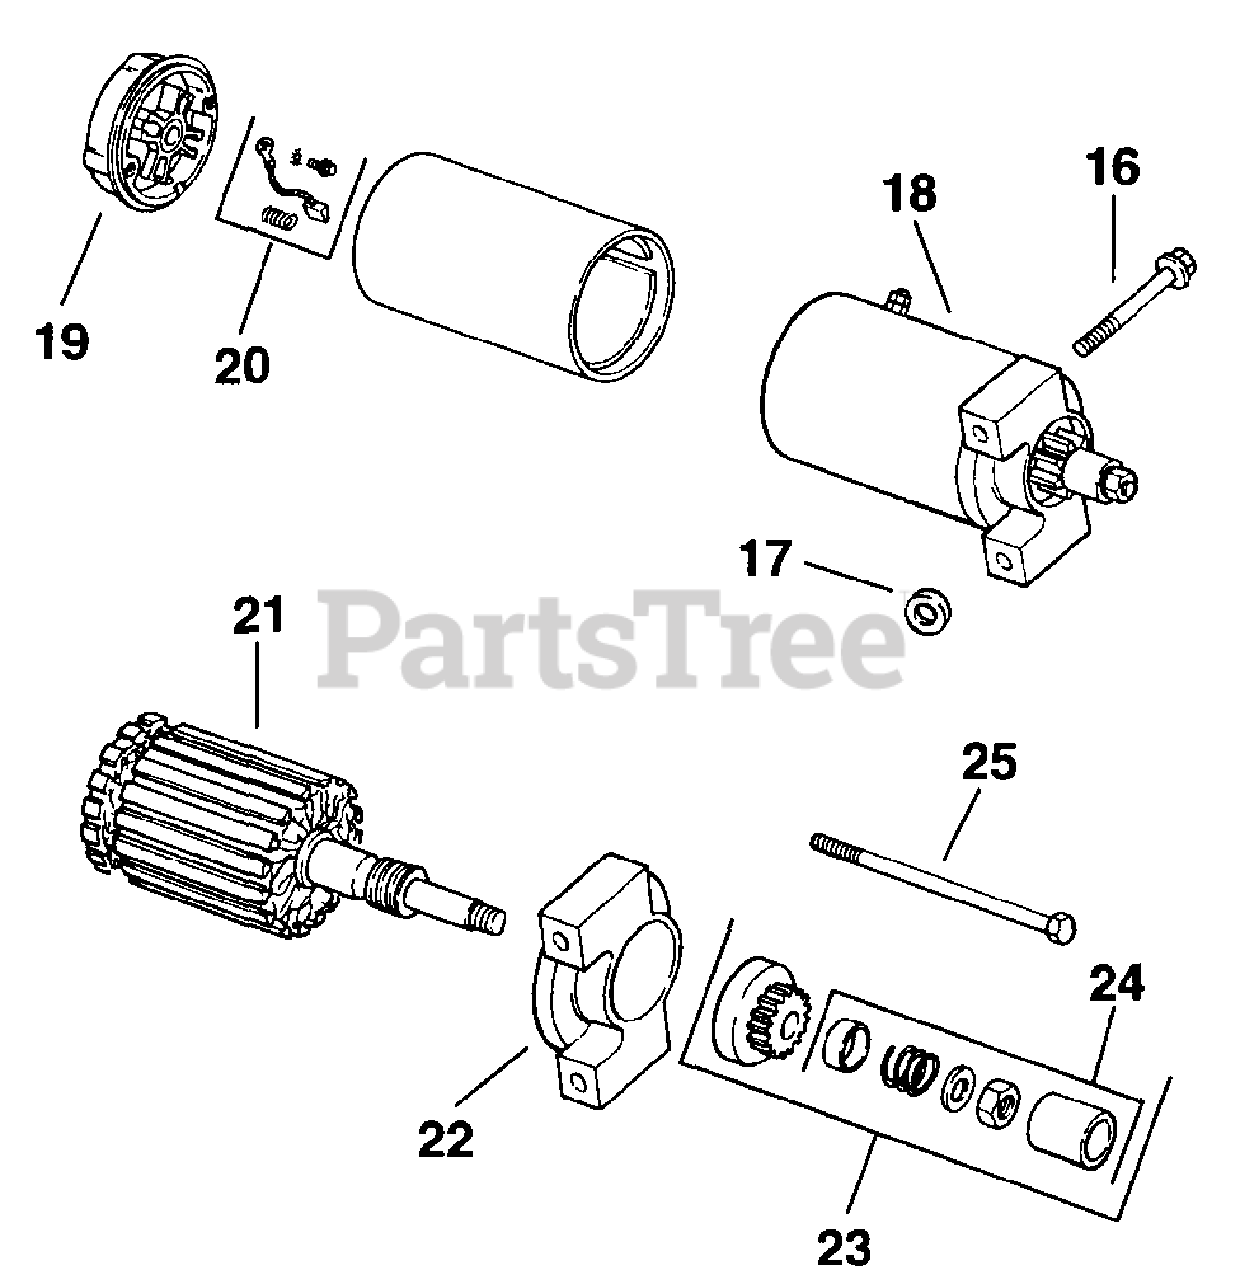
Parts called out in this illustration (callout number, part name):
16	SCREW - USE M-839070
17	WASHER, FLAT 11/32"
18	STARTER - USE 12 098 13
19	CAP - USE 12 227 11
20	KIT - USE 82 755 28
21	ARMATURE - DISCONTINUED
22	CAP - USE 12 227 05
23	DRIVE KIT - USE 12 755 53
24	DRIVE KIT - USE 12 755 53
25	SCREW - DISCONTINUED
5235701-S	Lubricant, Inertia Drive Starter (0.25 oz.)
